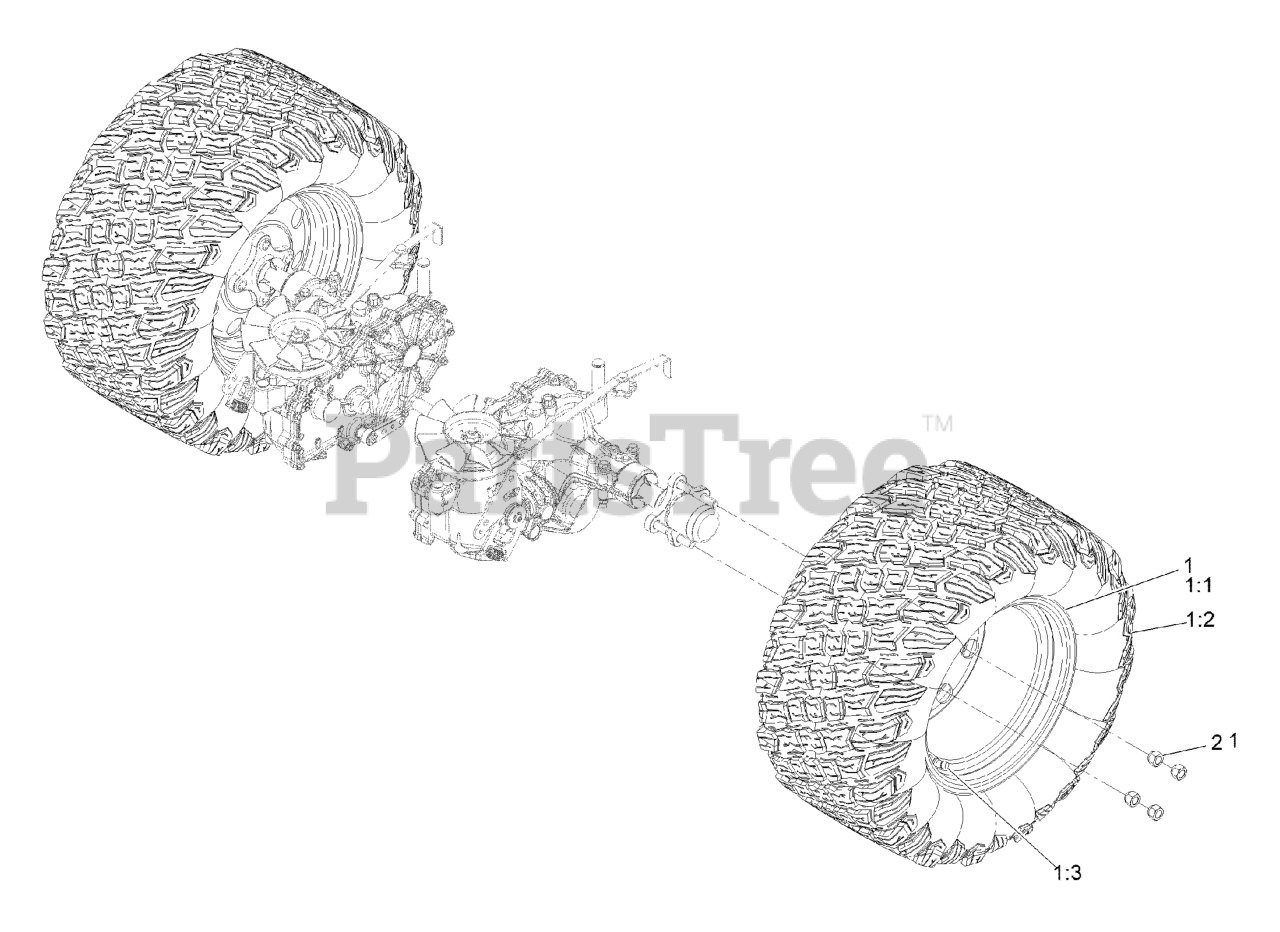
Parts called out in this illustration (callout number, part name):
1	ASM-WHEEL AND TIRE
1:2	Tire-Kenda K3012
1:3	VALVE
2	NUT-LUG
